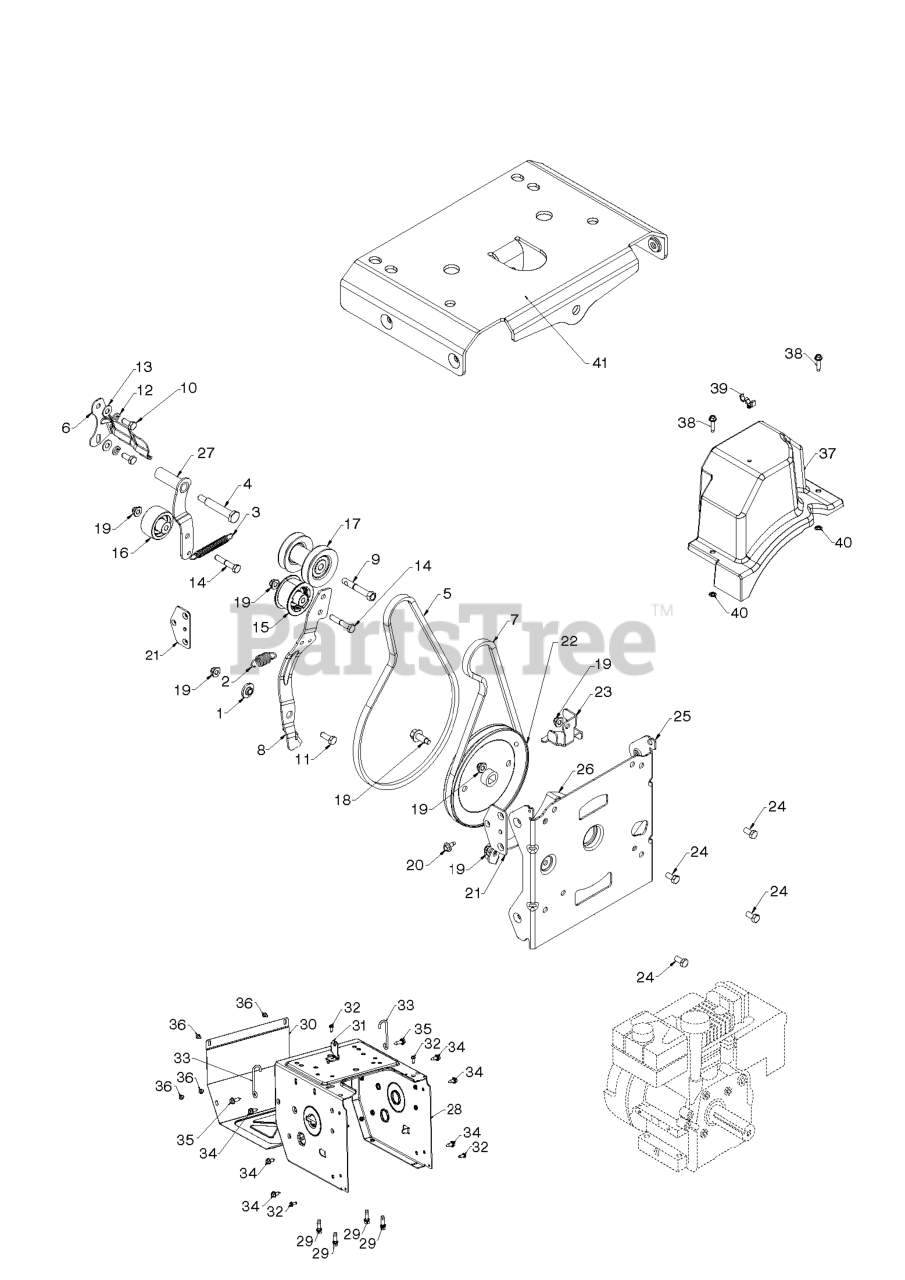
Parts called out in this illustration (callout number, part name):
1	BUSHING.BRAKE.ARM
2	SPRING RETURN, IDLER ARM, IMPE
3	SPRING RETURN IDLER ARM
4	BOLT 5/16-24X2.25 HEX HEAD SHO
5	BELT.HIGH.CRANK.4LX41.RAW.EDGE
6	BELT KEEPER BRACKET
7	HIGH CRANK IMPELLER BELT
8	ARM.IDLER.AUTO-PH.676
9	BOLT.ENGINE.PULLEY
10	SCREW 5/16-24 X .75 GR5
11	BOLT HEXAGON BOLT 5/16-18 X 7/
12	WASHER SPRING LOCK WASHER WITH
13	WASHER 11/32 X 11/16 X 14 GA T
13	WASHER M
14	BOLT, HEX 5/16-18X1-3/4
15	PULLEYIDLER.2.0.W/SPACER.CZ
16	PULLEY.IDLER.FLNGLESS.W/SPACER
17	PULLEY.ASM.IMPELLER/DRIVE
18	SCREW HEXAGON HEAD FLANGE 3/8-
19	NUTNYLOK.FLRANGE.5/16-18
20	HEX.WASHER.HEAD 1/4-20 X .65
21	BRACKET NUT BLACK ZINC PLATE
22	PULLEY IMPELLER DD 4L
23	GUIDE.LOWER.AUGER.BELT.479
24	BOLT, HEX HEAD 5/16-18
25	BRACKET.AUG.HOUSING.INTER.BLAC
26	BRACKET.BELT.KEEPER.LOWER.BLAC
27	ARM IDLER DRIVE WELDMENT_HOT
28	FRAME MS 668
29	BOLT 3/8-16X1-1/8
30	COVER COVER.FRAME MS668 ORANGE
31	BRACKET.SHIFTER.BZP
32	SCREW.HEX HEAD W/COLLAR 1/4-20
33	WIREFORM.SUPPORT.CABLE
34	BOLT.HEX.HD.WASHER.5/16-18X.75
35	SCREW HEXAGON HEAD WITH COLLAR
36	SCREW.HEX HEAD W/COLLAR 1/4-20
37	COVER BELT ASM HIGH CRANK
41	BRACKET.FRAME.SUP.LARGEENG.BLA
